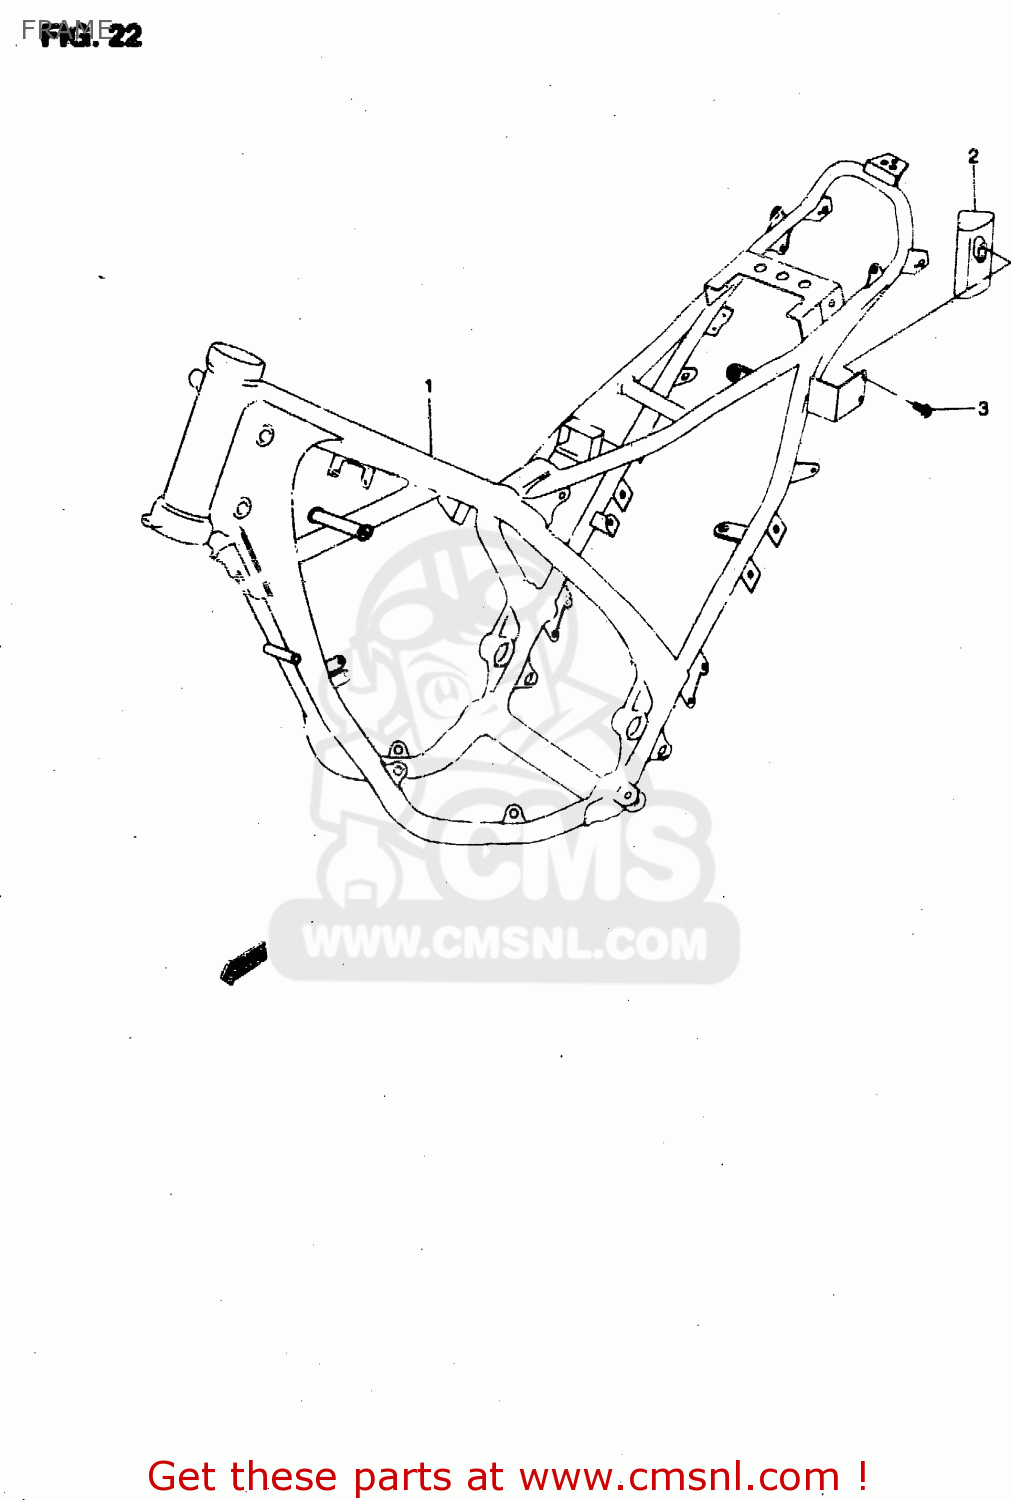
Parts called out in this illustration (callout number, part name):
1	FRAME (GREY)
2	TOOL CASE
3	SCREW
